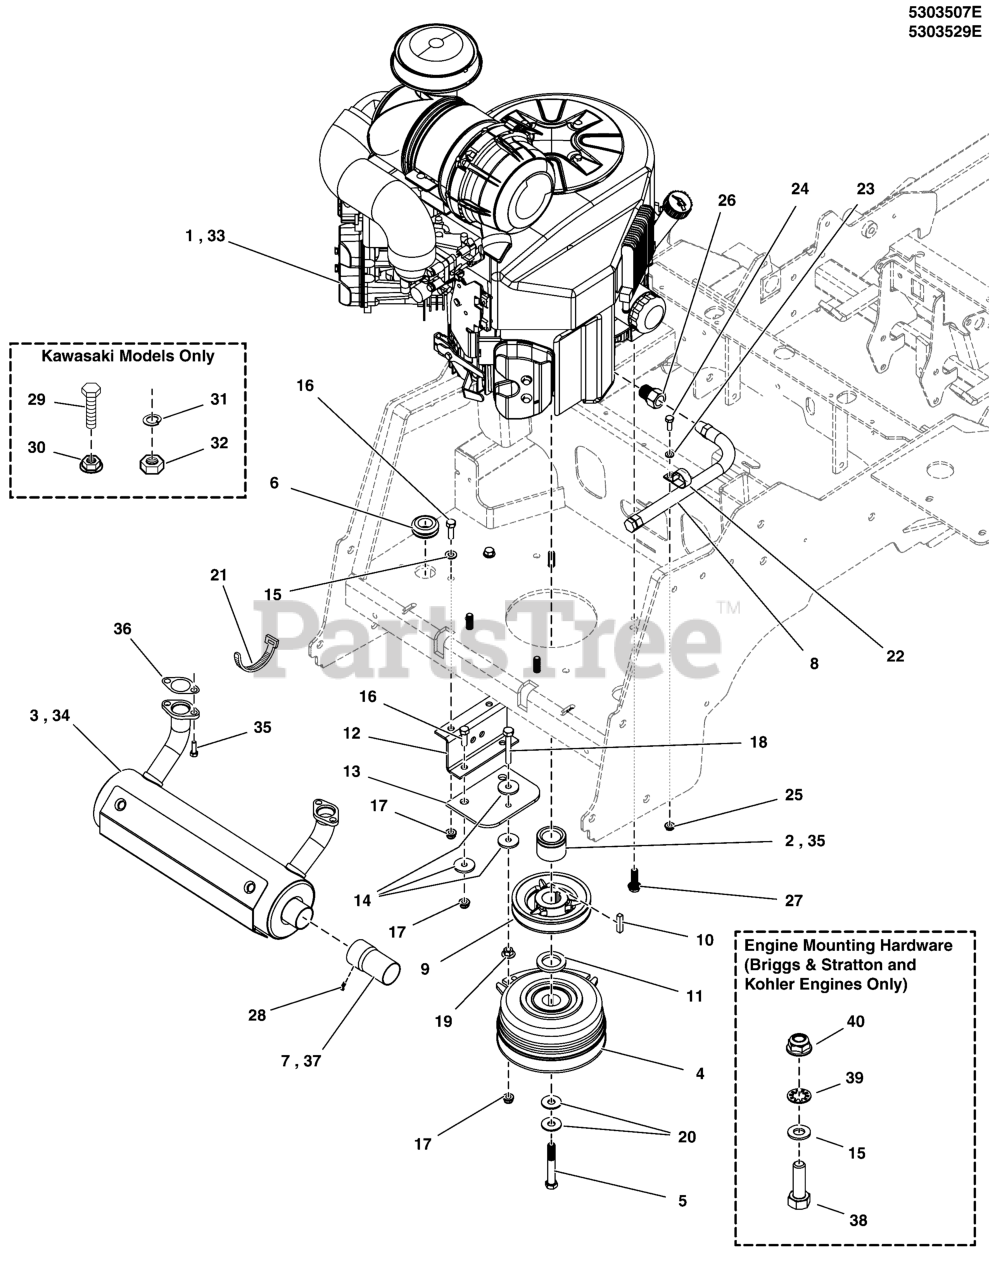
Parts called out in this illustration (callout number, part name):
2	SPACER, 1.13 X 1.75 X 1.35, CZ
3	MUFFLER, 27HP KAWASAKI, 5" CAN
4	CLUTCH WARNER 200 FT-LB 1.13 X 6.323
5	BOLT, CRANKSHAFT, 7/16-20 X 3, GD8
6	GROMMET, 7/8"ID, 1/4" THICK STK
7	EXTENSION, TAILPIPE, 3"
8	HOSE, OIL DRAIN
9	PULLEY, 4.75 OD X 1-1/8 BORE, BC-48
10	KEY, 1/4" SQ. X 1-1/4
11	SPACER, 1.13 x 1.75 x .25
12	ANCHOR, CLUTCH, IS600-IS700 - BLK
13	CLUTCH ANCHOR PAD
14	WASHER, .34 X 1.25 X 10 GA
15	WASHER, 5/16" SAE
16	BOLT, 5/16-18 X 1" GRD5 YZ
17	NUT, 5/16-18 HEX NYLOCK FLANGE NUT
18	BOLT, 5/16-18 X 2-1/4 TFL, GD5 YZ
19	NUT, 5/16-18 HEX SERRATED FLANGE (LARGE)
20	BELLEVILLE WASHER, 1.1875 X .442 X .098
21	TIE,SELF-LOCKING, 24"
22	CLAMP, VINYL INSULATED, 1.00
23	WASHER, 1/4 SAE
24	BOLT, 1/4"-20 X 3/4" GD5 YZ
25	NUT, 1/4-20 HEX SERR. FLANGE
26	ADAPTER, Oil Drain
27	BOLT, HEX FLG, SER, GD5 3/8-16 X 1-1/4" PACH CZ
28	SCREW, SELF-TAP, #8-32 X 3/8. WASH HEX, CZ
29	WASHER, 5/16 LOCK CZ
30	NUT, HEX, M8-1.25, CZ, GD 8.8
31	NUT, M8-1.25 Hex Serrated Flange
32	BOLT, M8-1.25 X 16MM GD8.8
33	ENGINE, 26HP, B&S, VANGUARD
34	MUFFLER, RIGHT OUTLET ASSY
35	SCREW
36	GASKET, EXHAUST
37	EXTENSION, TAILPIPE, 3" - BLACK
38	BOLT, 5/16-24 X 1-3/4, GD8, PHOS
39	WASHER, 5/16" Internal Tooth Lock
40	NUT, 5/16-24, TOP LOCK FLANGE, GD8 PHOS
